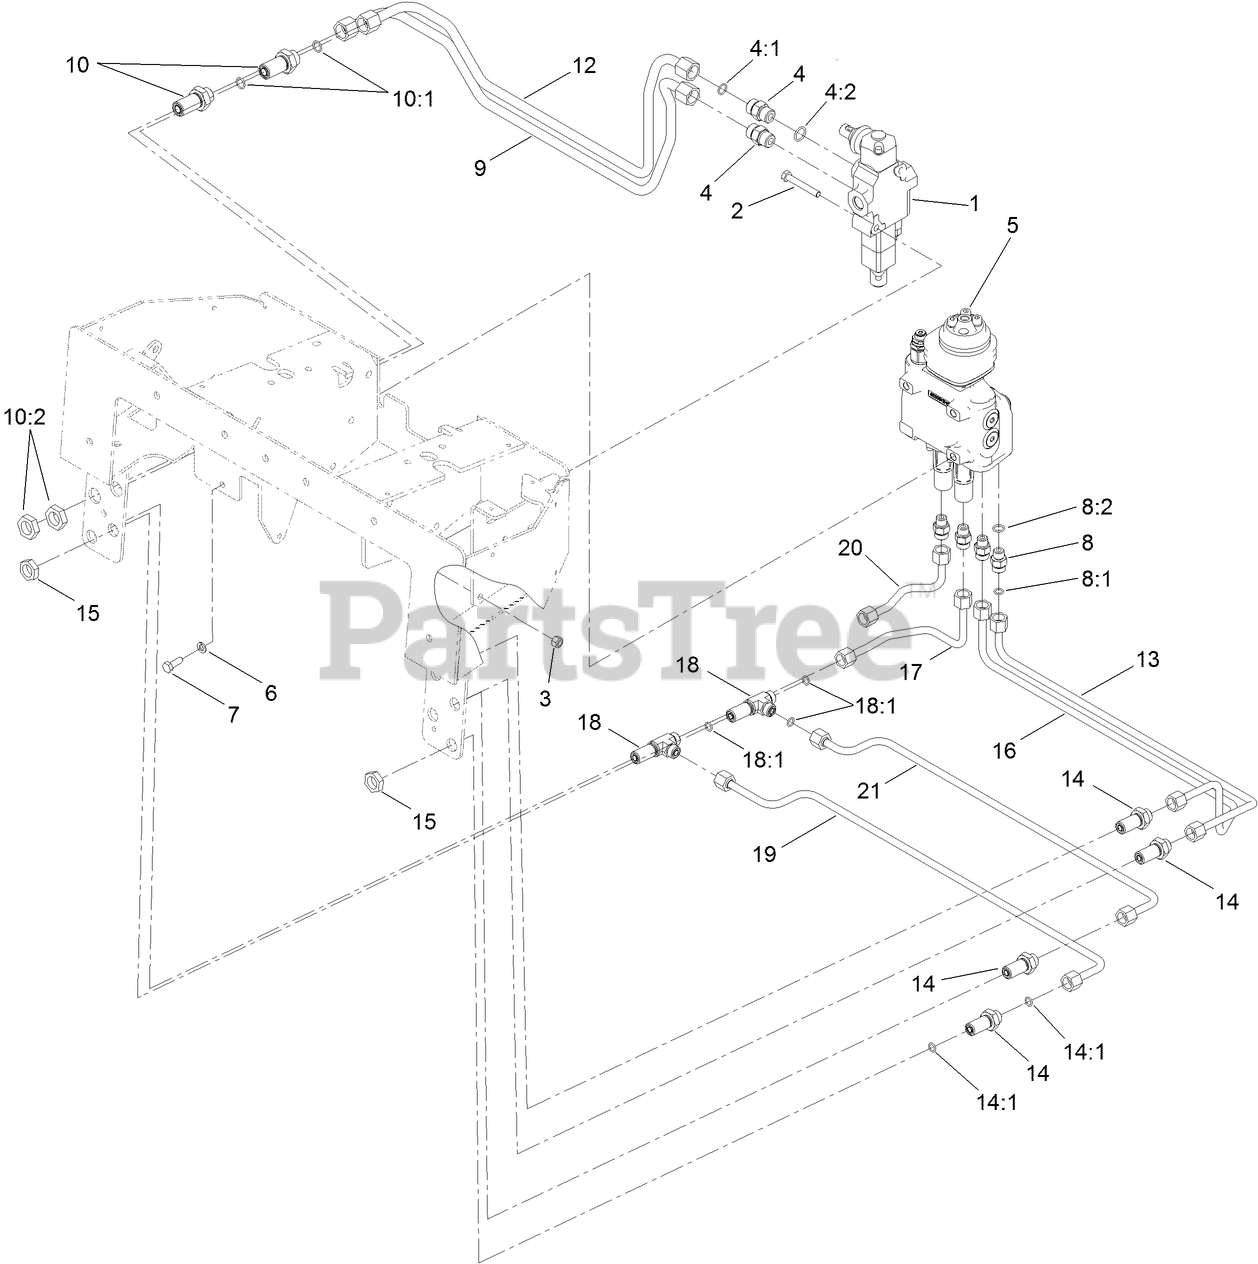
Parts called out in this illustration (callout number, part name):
1	1 SPOOL VALVE ASM
2	SCREW-HH
3	NUT-LOCK, NI
4	FITTING-STRAIGHT
4:1	O-RING
4:2	O-RING
5	2 SPOOL VALVE ASM
6	WASHER-LOCK
7	SCREW-HH
8	FITTING-STRAIGHT
8:1	O-RING
8:2	O-RING
9	TUBE-HYD
10	FITTING-BULKHEAD
10:1	O-RING
10:2	NUT-BULKHEAD
12	TUBE-HYD
13	TUBE-HYD
14	FITTING-STRAIGHT, BULKHEAD
14:1	O-RING
15	NUT-LOCK
16	TUBE-HYD
17	TUBE-HYD
18	FITTING-TEE, BULKHEAD
18:1	O-RING
19	TUBE-HYD
20	TUBE-HYD
21	TUBE-HYD
